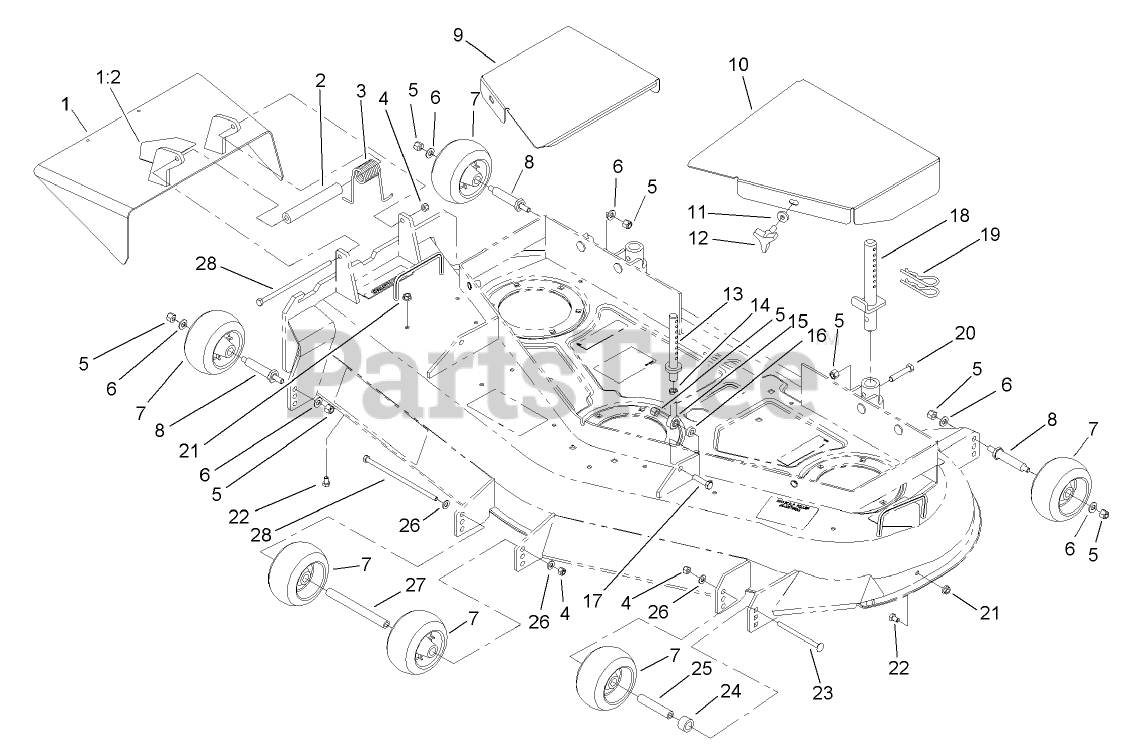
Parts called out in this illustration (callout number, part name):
1	Deflector ASM
1:2	DECAL-DANGER
2	SPACER
3	SPRING-TORSION
4	NUT-LOCK, NI
5	NUT-LOCK, NI
6	WASHER-FLAT
7	WHEEL-GAGE
8	SPACER
9	COVER-BELT, RH
10	COVER-BELT, LH
11	WASHER-RUBBER
13	FRONT PIN ASM
14	NUT-HJ
15	BALLJOINT
16	SPACER
17	SCREW-HH
18	REAR PIN ASM
19	PIN-HAIR
20	SCREW-HH
21	NUT-HF
22	SCREW-HH
23	SCREW-CARR
24	SPACER-WHEEL
25	BUSHING-ROLLER
26	WASHER-PLAIN
27	SPACER-WHEEL
28	SCREW-HH
